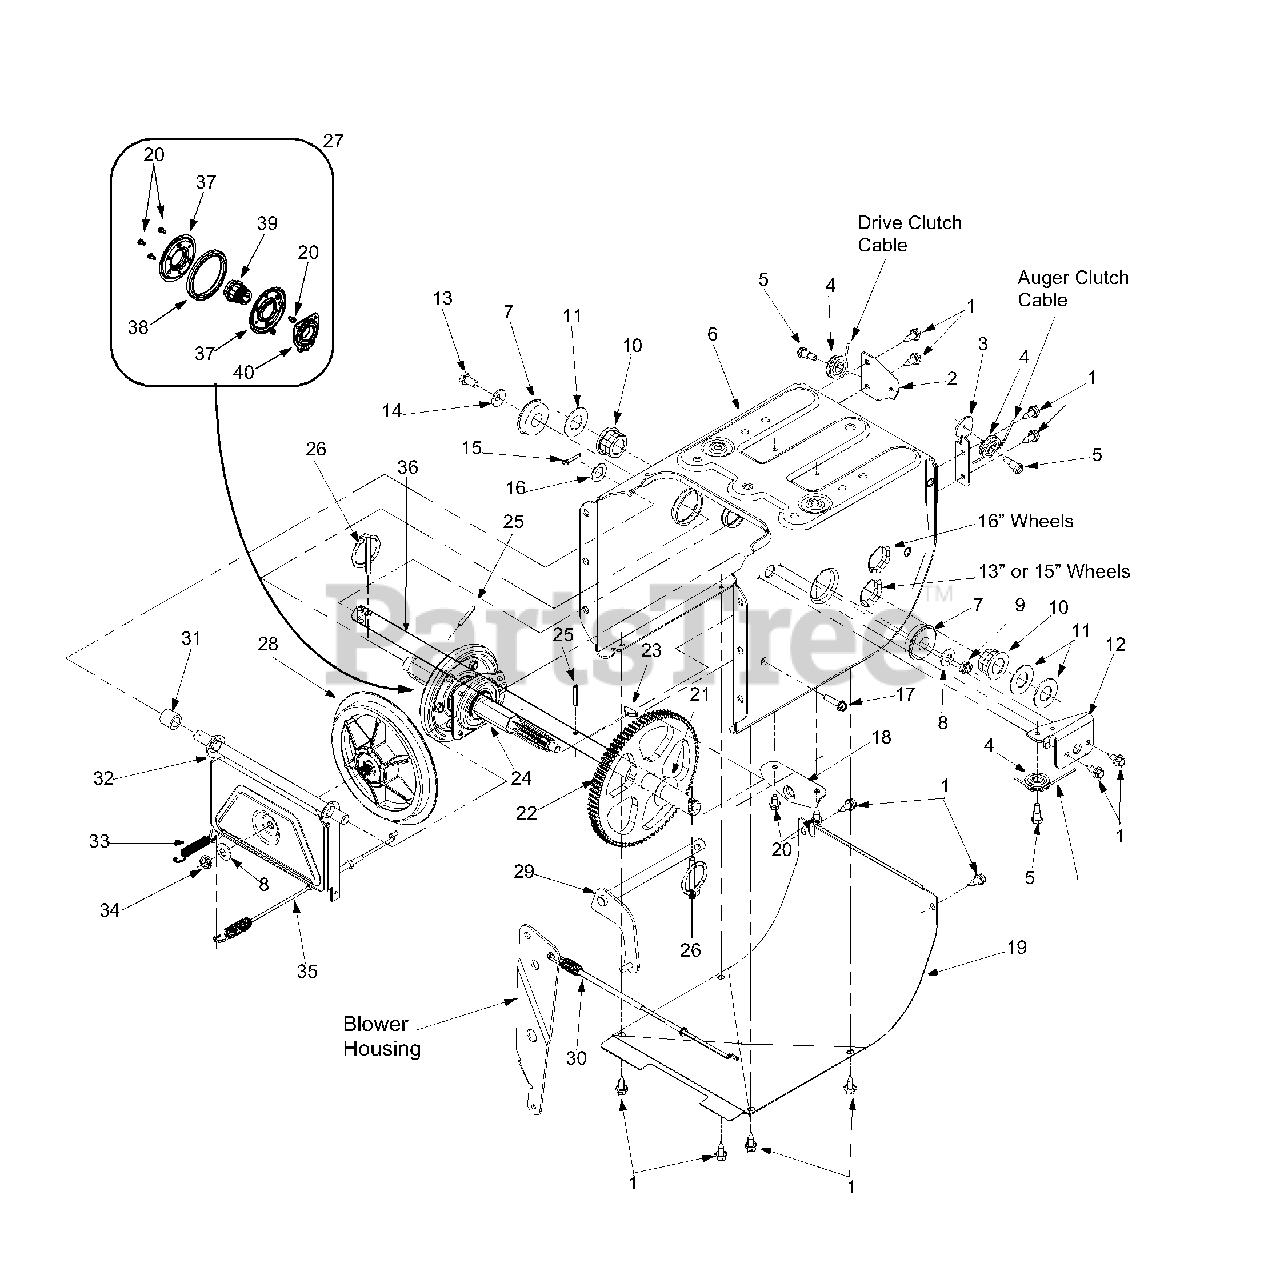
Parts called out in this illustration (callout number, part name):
1	Hex Screw
5	Hex Screw 1/4-28
8	Bell Washer
9	Lock Jam Nut
10	Hex Flange Bearing
11	Flat Washer
14	Bell Washer .340 ID x .872 OD
15	Cotter Pin
16	Flat Washer .536 ID x .930 OD
17	Hex Washer Screw 1/4-20
21	Flat Washer .760 ID x .50 OD
24	7-Tooth Shaft
25	Roll Pin
26	Klik Pin
27	Friction Wheel Assembly
28	Friction Disc Wheel
29	Wheel Shift Rod Assembly
30	Drive Cable
31	Spacer
34	Jam Nut 3/8-24
35	Drive Cable
36	Axle 13" Wheels
37	Friction Plate
38	Friction Wheel Rubber
39	Friction Wheel Hub
40	Friction Wheel Bearing
